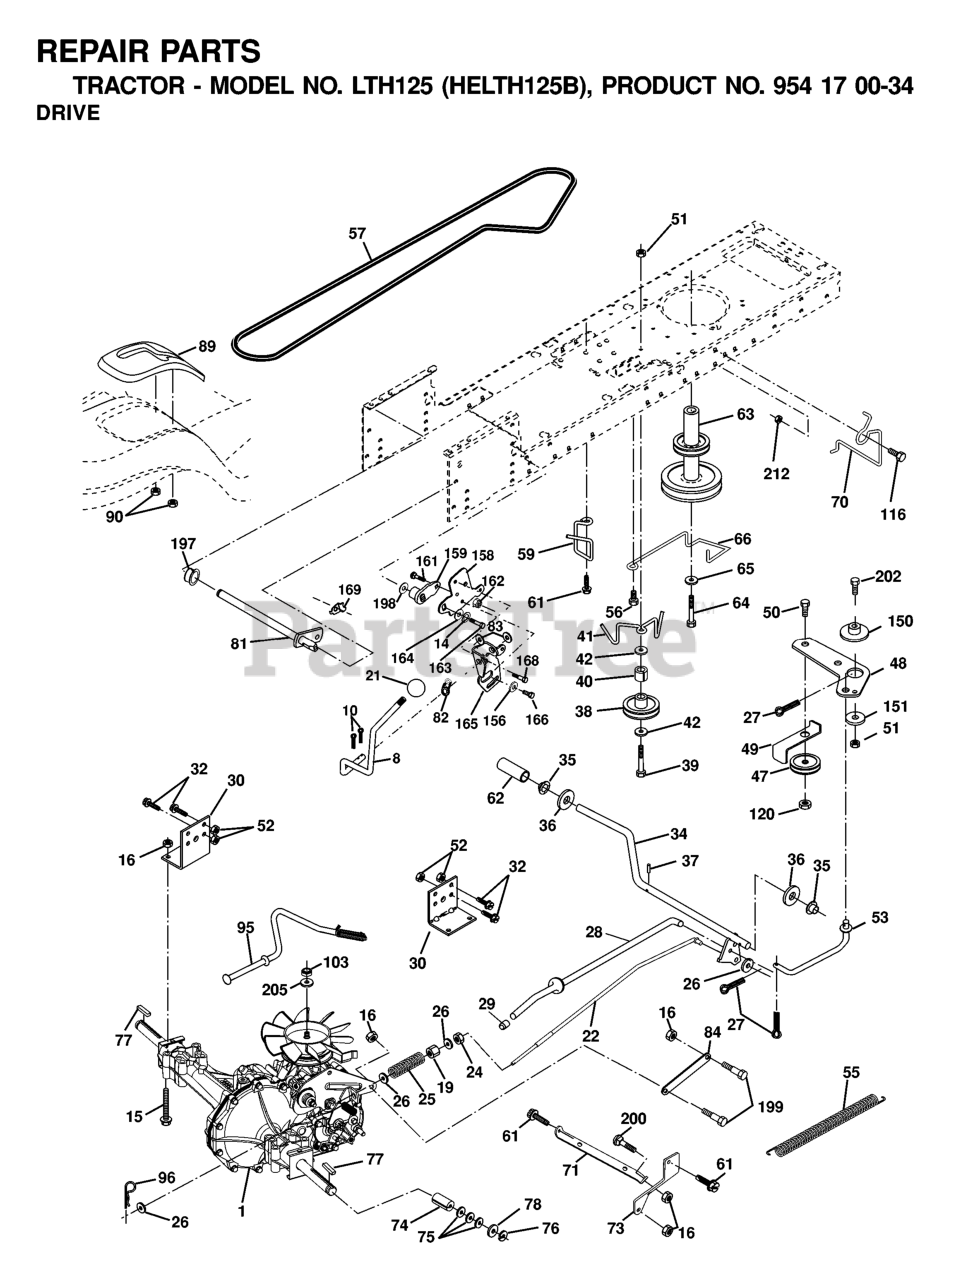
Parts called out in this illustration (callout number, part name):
8	ROD SHIFT FENDER ADJUST STLT
10	PIN COTTER
14	LOCKWASHER
15	BOLT HEX 5/16-18 GR 5
16	NUT.71038.31-18.HEX.NYLOCK
19	NUT
21	KNOB.DUCKHEAD.1/2
22	ROD BRAKE HYDRO
24	NUT
25	SPRING ROD LT
26	WASHER
27	COTTER PIN
28	ROD, PARKING BRAKE
29	PLUNGER CAP
30	BRKT, MOUNT TRNSAXLE
32	BOLT
34	SHAFT, FOOT PEDAL
35	BEARING.NYLON
37	DRIVE PIN
38	PULLEY.FLAT
39	BOLT
40	SPACER, SPLIT
41	KEEPER, BELT IDLER
42	WASHER
47	IDLER PULLEY
48	BELLCRANK, CLUTCH
49	RETAIN BELT
50	BOLT
52	LOCKNUT
53	LINK, CLUTCH LT
55	SPRING, RETURN LT
56	SCREW THDROL 3/8-16 X 1-1/2
57	DRIVE BELT, LTH & YTH TRACTORS
59	KEEPER, BELT CENTER
61	SCREW 3/8-16X3/4
62	PEDAL COVER T
63	ENGINE PULLEY
64	BOLT
65	LOCKWASHER
66	KEEPER BELT ENGINE
70	KEEPER BELT ENG
71	STRAP TORQUE LH HYDRO
73	STRAP TORQUE RH HYDRO
74	SPACER AXLE
77	SQUARE KEY
81	SHAFT ASM CROSS TAPERED
82	SHIFT SPRING
83	WASHER
84	LINK TRANSAXLE
89	SHIFT CONSOLE
90	NUT.PUSH.3/16
95	CONTROL ASM. BYPASS HYDRO
96	RETAINER M
103	NUT.HEX.1/2-20
116	BOLT D
120	NUT LOCK FLG 3/8-16 UNC
150	SPACER, RETAINER
151	WASHER 12/32X2X10GA
156	WASHER.SRRTD.5/16
158	BRACKET
159	HUB
161	BOLT
162	NUT.CROWNLOCK.1/4
164	Washer 5/8 x .281 x 10 Ga.
165	RP BRACKET
168	BOLT.SHOULDER.5/16-18X
169	PLATE.FASTENING.CROSS.SHAFT
197	NYLINER SNAP 5/8" ID
198	WASHER.NYL.7/8IDX.105"HYD CR
199	BOLT SHOULDER 5/16-18 UNC
205	WASHER
212	NUT
